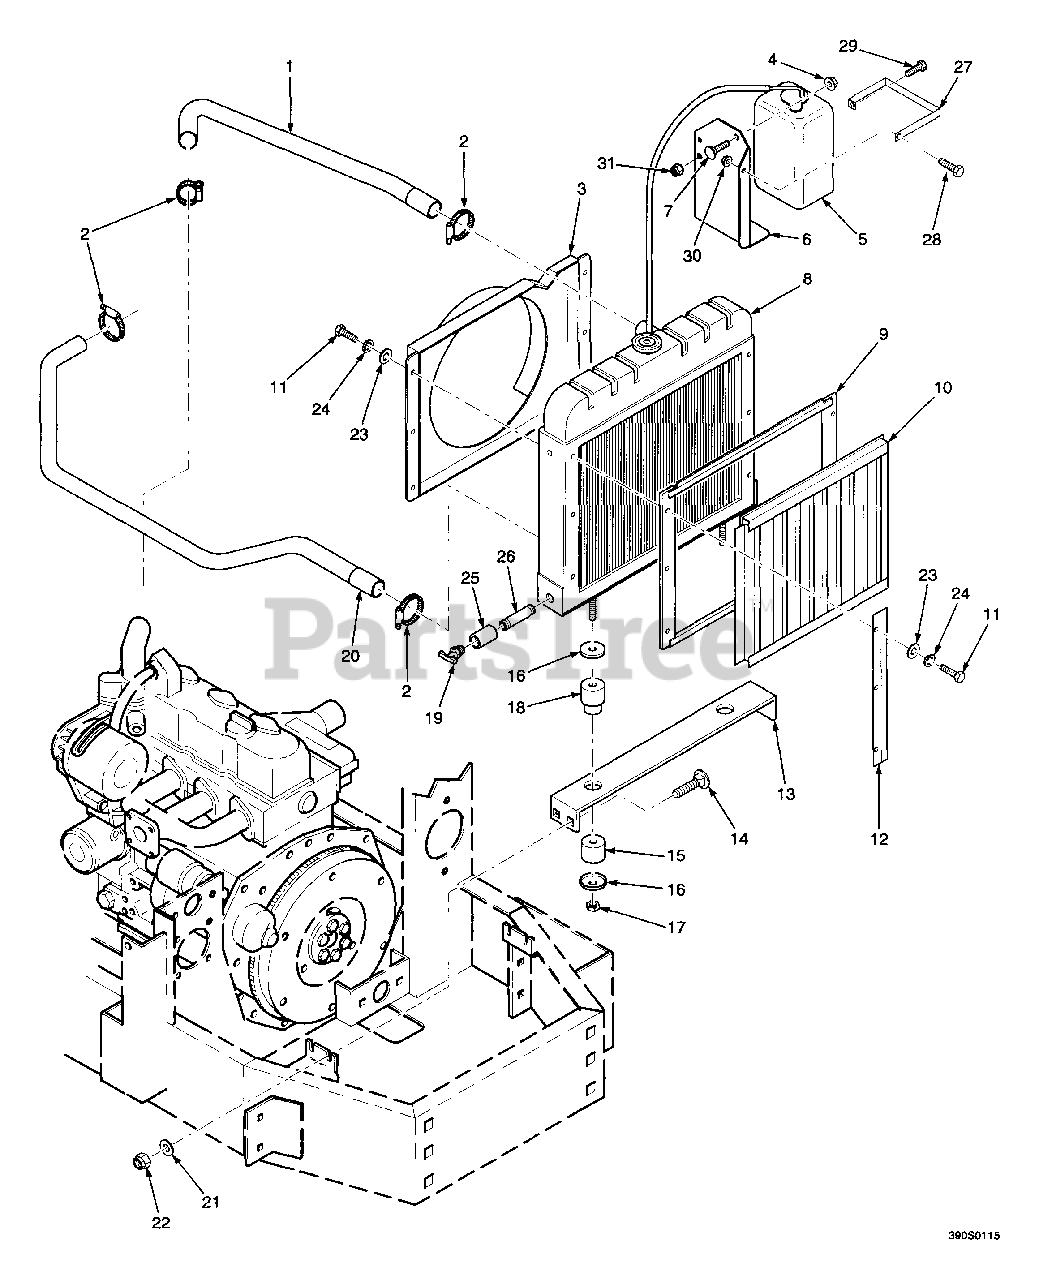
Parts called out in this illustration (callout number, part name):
1	Hose, Upper Radiator
2	Clamp, Hose
3	Shroud, Fan
4	Serr. Fl Hex Nut, 5/16-18
5	Tank, Coolant Overflow
6	Mounting Bracket, Coolant Tank
7	Carriage Bolt, 5/16-18 x .75
8	Radiator with Oil Cooler
9	Frame, Debris Screen
10	Screen. Debris
11	Bolt, Hex Head, 1/4-20 X 5/8
12	Side Rail, Debris Screen
13	Bracket, Radiator Mounting
14	Carriage Bolt, 3/8-16 x 1-1/4
15	Cushion, Radiator Mounting
16	Washer, Radiator Mounting
17	Locknut, 3/8-16
18	Cushion, Radiator Mounting
19	Drain Cock
20	Hose, Lower Radiator
21	Flatwasher, 3/8 (.391 x .938 x 105)
22	Hex Locknut, Elastic Stop, 3/8-16
23	Flatwasher, 1/4 (.312 x .75 X .065)
24	Lockwasher, 1/4
25	Coupling, 1/4 NPT
26	Nipple, 1/4 NPT x 2.0
27	Strap, Coolant Bottle
28	Bolt, Hex Head, 1/4-20 x .50
29	Bolt, Hex Head, 1/4-20 x 1 25
30	Serr. Fl Hex Nut, 1/4-20
31	Hex Locknut, Elastic Stop, 1/4-20
